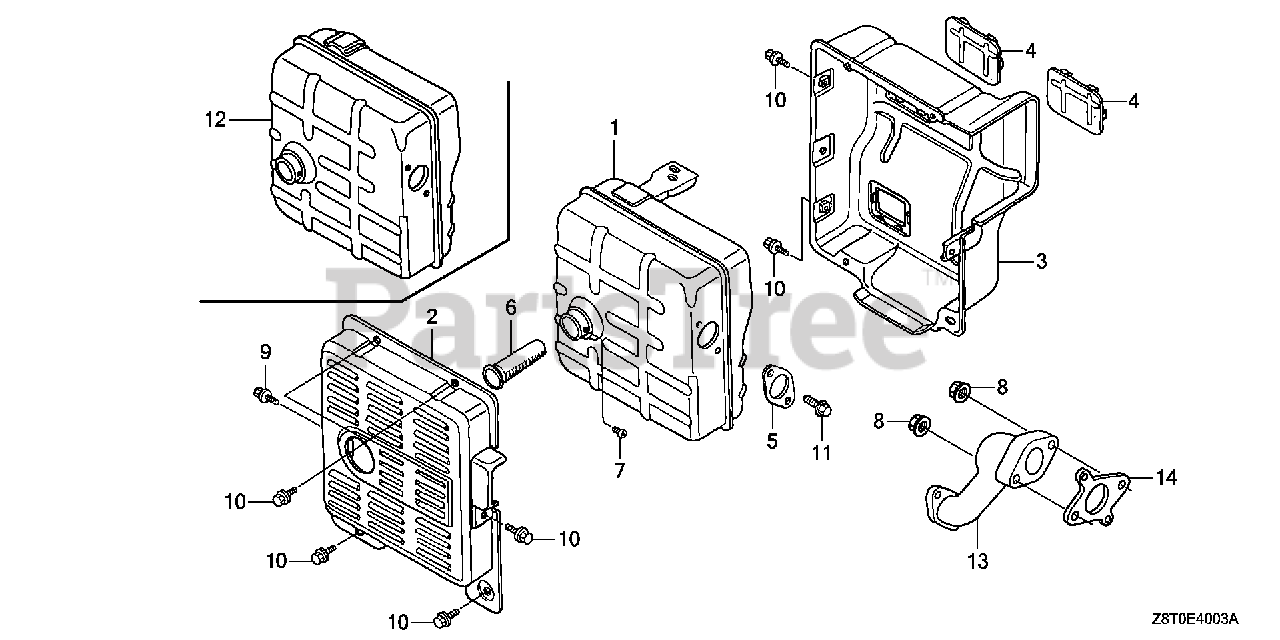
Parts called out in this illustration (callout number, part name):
2	PROTECTOR, MUFFLER (OUTER)
3	PROTECTOR, MUFFLER (INNER)
4	SEAL, MUFFLER PROTECTOR
5	GASKET, EX. PIPE
6	ARRESTER, SPARK
7	SCREW, TAPPING (4X8)
8	NUT, FLANGE (8MM)
11	BOLT, FLANGE (8X20) Use up to Engine SN 1609606.
12	MUFFLER (TSURUMI)
14	GASKET, EX. PIPE
